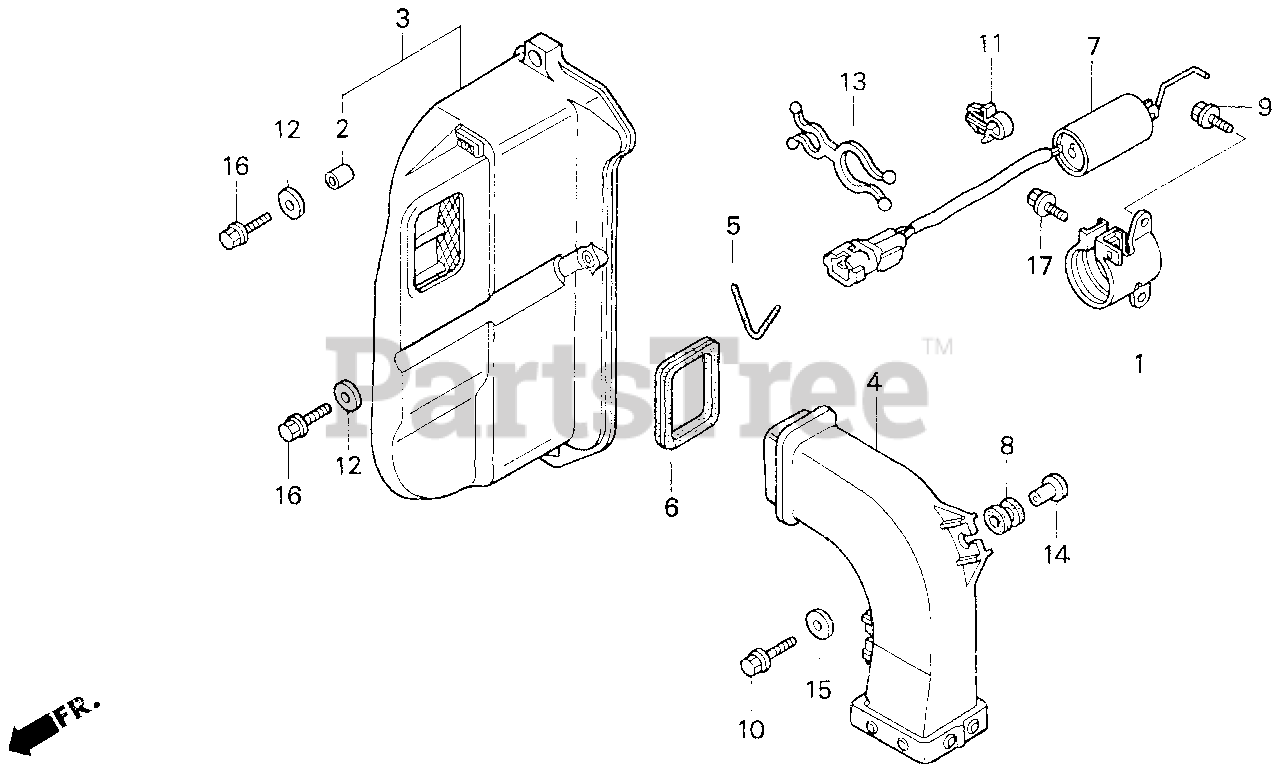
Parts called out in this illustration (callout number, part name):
1	STAY, SOLENOID
2	COLLAR, DISTANCE
3	COVER, MUFFLER
4	DUCT, MUFFLER
5	GASKET, MUFFLER COVER
6	GROMMET, MUFFLER DUCT
7	SOLENOID ASSY., REMOTE CHOKE
8	GROMMET, CASE (LOWER)
9	BOLT, FLANGE (6X14)
10	BOLT, FLANGE (6X25)
11	HOLDER, ROD (6MM)
12	WASHER (6MM)
14	COLLAR, IGNITION CONTROL MODULE CASE
14	COLLAR, MODULE IGNITION CONTROL CASE (CDI)
15	WASHER, PLAIN (6MM)
16	BOLT, FLANGE (6X25)
17	BOLT, FLANGE (6X12)
